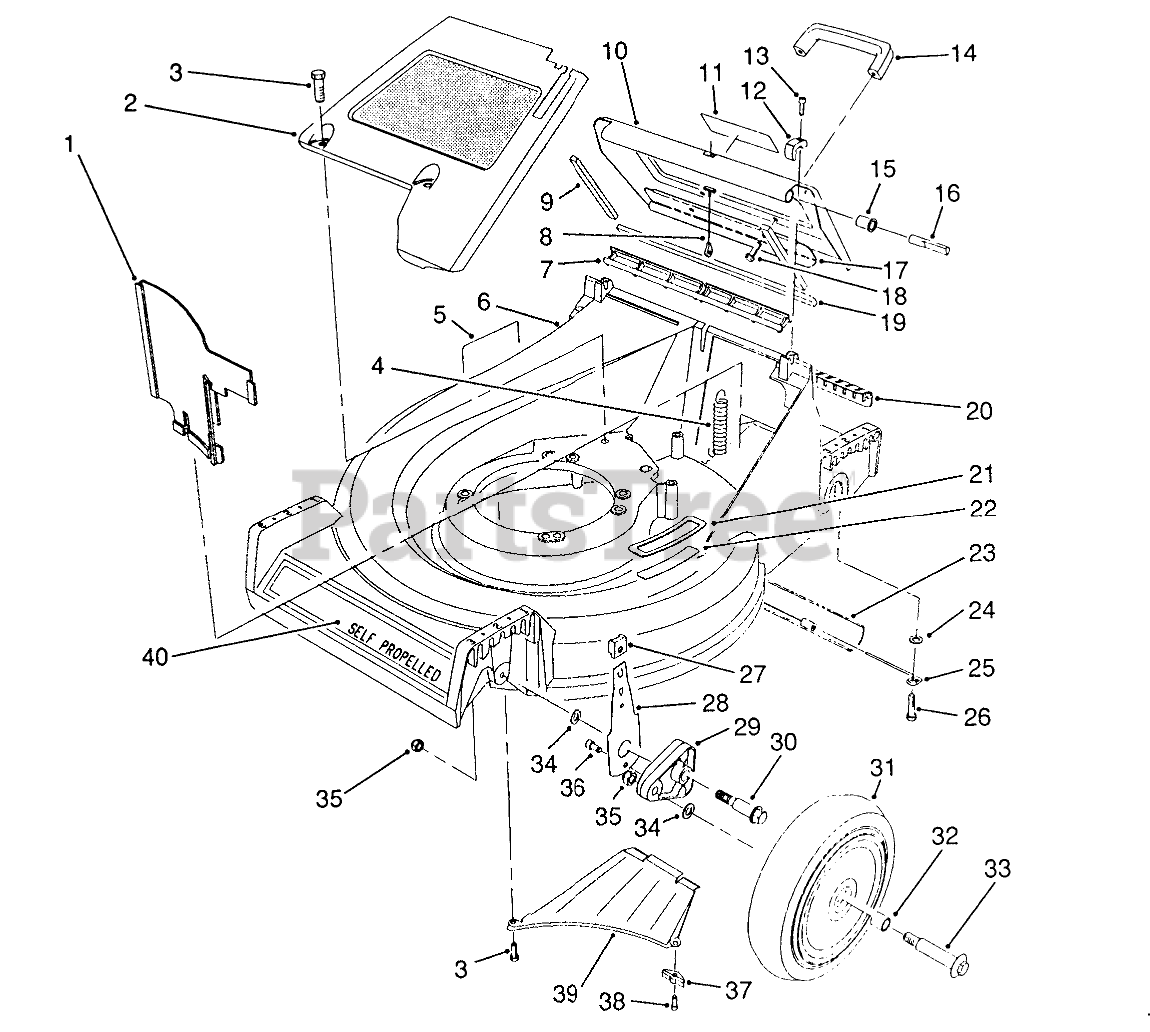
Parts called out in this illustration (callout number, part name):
1	PANEL-VERTICAL
2	PaneI-Screen
3	SCREW-HWHTF
4	EXTENSION-SPRING
5	DECAL-DANGER
6	21" Housing Assembly (Incl. Ref. #5, 21-22)
7	DOOR SEAL
8	DOOR CABLE
9	DOOR SIDE SEAL
10	Door-Discharge (Incl. Ref. #9, 11, 17 & 19)
11	DECAL - WARNING
12	HINGE CLAMP
13	SCREW-HSH
14	HANDLE-DOOR
15	DOOR BUSHING
16	HINGE PIN
17	DOOR - BRACE
18	SCREW-HWH
19	DOOR END SEAL
20	ACCESS COVER
21	STEP PAD
22	STEP PAD DECAL
23	TRAILING SHIELD
24	WASHER-PLAIN
25	SHIELD HANGER
26	SCREW-SHOULDER
27	KNOB-ARM
28	FRONT SPRING ARM ASM
29	ARM-PIVOT, FRONT
30	BOLT-SHOULDER
31	Wheel & Tire Assembly (Incl. Ref. #30)
32	BUSHING
33	WHEEL BOLT
34	WASHER
35	Nut
36	SCREW-HSH, THREAD FORMING
37	Bracket-Discharge
38	SCREW-HWHTF
39	Ramp Discharge
40	DECAL - DECK
